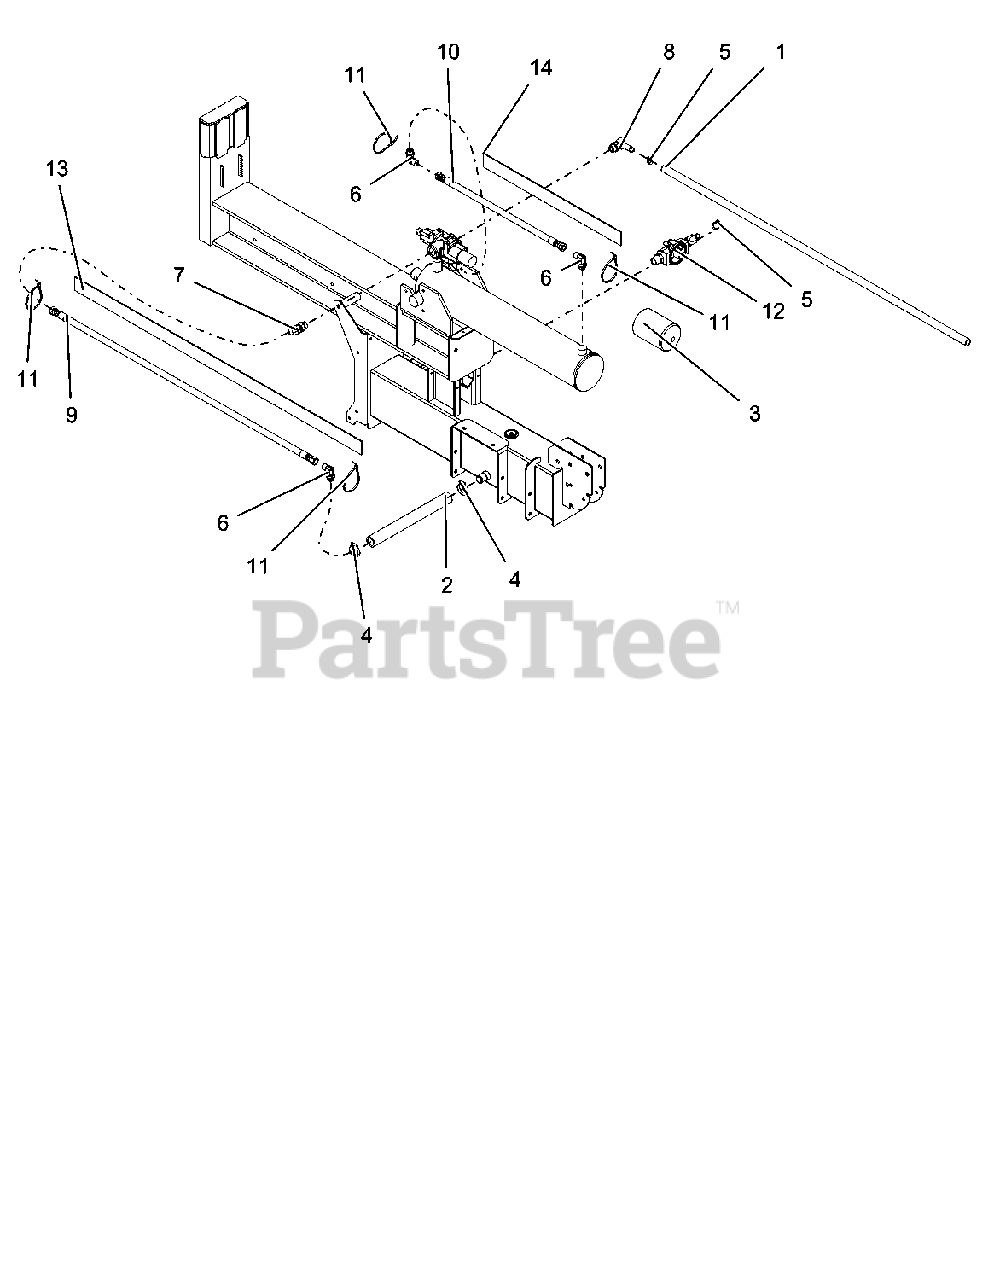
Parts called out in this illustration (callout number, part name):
1	HOSE, HYD RETURN 10L0LA X 53"
2	HOSE, HYD SUCTION 16G4H X 13.5
3	FILTER, HYDRAULIC OIL-NO BYPASS
4	CLAMP, HOSE 1.50 X .81 X 1.42
5	CLAMP, .88 DIA HOSE
6	FTG, HYD. 2501-8-8
7	FTG, HYD. 6802-8-10
8	FTG, HYD. 4601-10-10
9	HOSE, ASM - 46"
10	HOSE, ASM - 22"
11	CABLE, TIE 5.50 LG
12	ASM, FILTER HEAD
13	SLV, PROTECTIVE -50"
14	SLV, PROTECTIVE -24"
